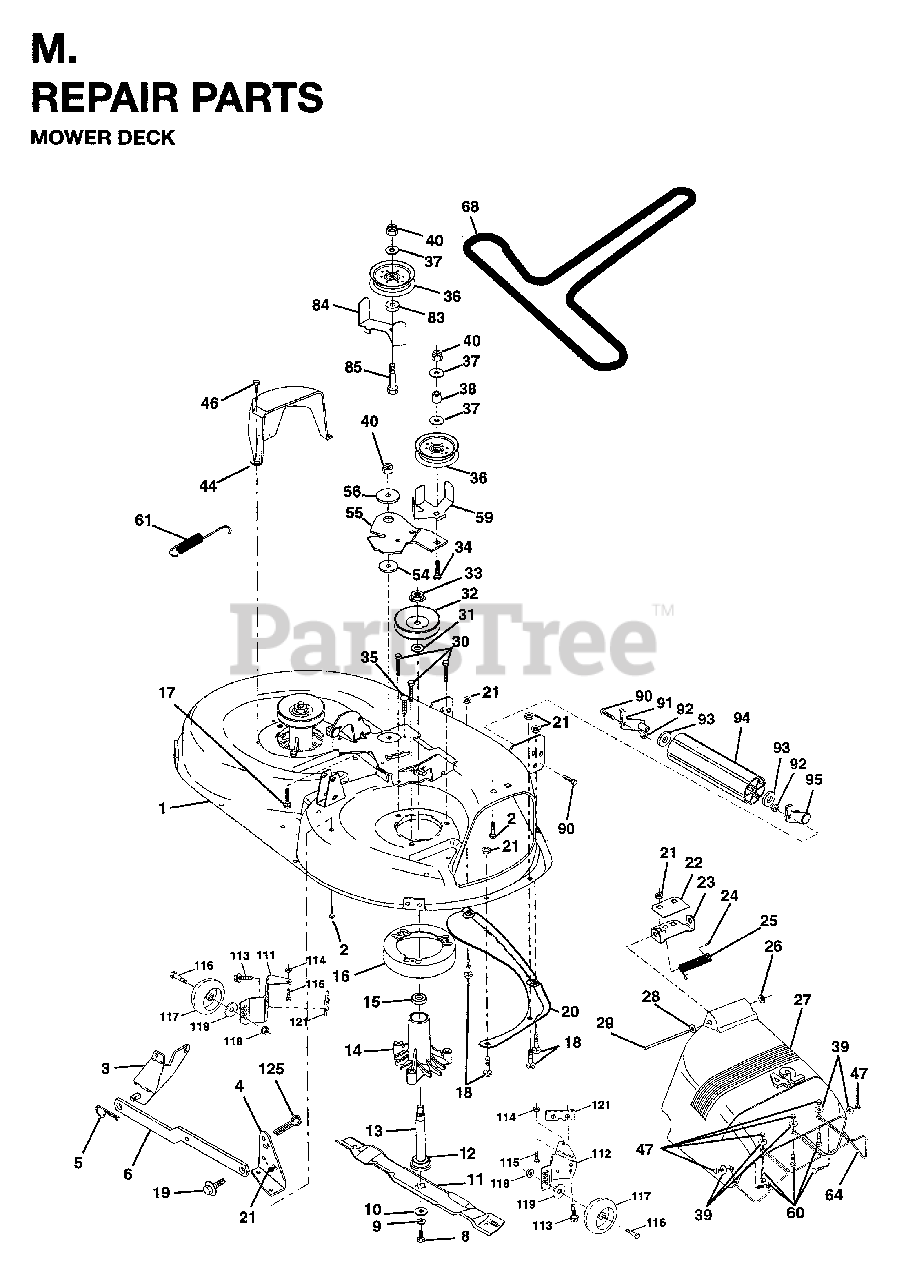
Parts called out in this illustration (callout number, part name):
1	DECK 42"
2	BOLT
3	BRKT ASM SWAY BAR
4	BRKT DECK SW BAR
5	RETAINER SPRING
6	REAR SUSP ARM
8	BLADE BOLT
9	WASHER, LOCK 3/8
10	WASHER.BLADE
11	BLADE 42"
12	BEARING
13	SHAFT ASM VENT
14	HSG MANDREL
16	STRIPPER
17	BOLT CARRIAGE
18	BOLT
19	BOLT SHD 5/16-18
20	BAFFLE
21	LOCKNUT
22	STIFFENER BRACKET
23	DEFLECTOR BRACKET
24	CAP-SLEEVE LT
25	SPRING TORSION
26	NUT PUSH M
28	WASHER - 15X7.3X1.6
29	ROD.HINGE
30	SCREW
31	WASHER
32	MANDREL PULLEY
33	NUT
35	FASTENER.XMAS.TREE
36	FLAT IDLER PULLEY
37	WASHER
38	IDLER SPRING SPACER
39	WASHER
40	LOCKNUT
44	GUARD MANDREL LH BLACK
46	SCREW.1/4-20X5/8
47	NUT
54	HARDENED WASHER
55	IDLER ARM
56	SPACER RETAINER
59	GUARD, BELT
60	SCREW.10-24X5/8
61	SPRING EXTENSION
68	V-BELT TRIPATH
84	KEEPER BELT
85	BOLT
91	BRACKET LH (A)
92	LOCKNUT
94	NOSE ROLLER
95	BRACKET RH (B)
111	BRACKET
112	BRACKET
113	BOLT
114	LOCKNUT
118	LOCKNUT
119	WASHER
121	BRACKET.EXTRD.GWL
125	COTTER PIN
